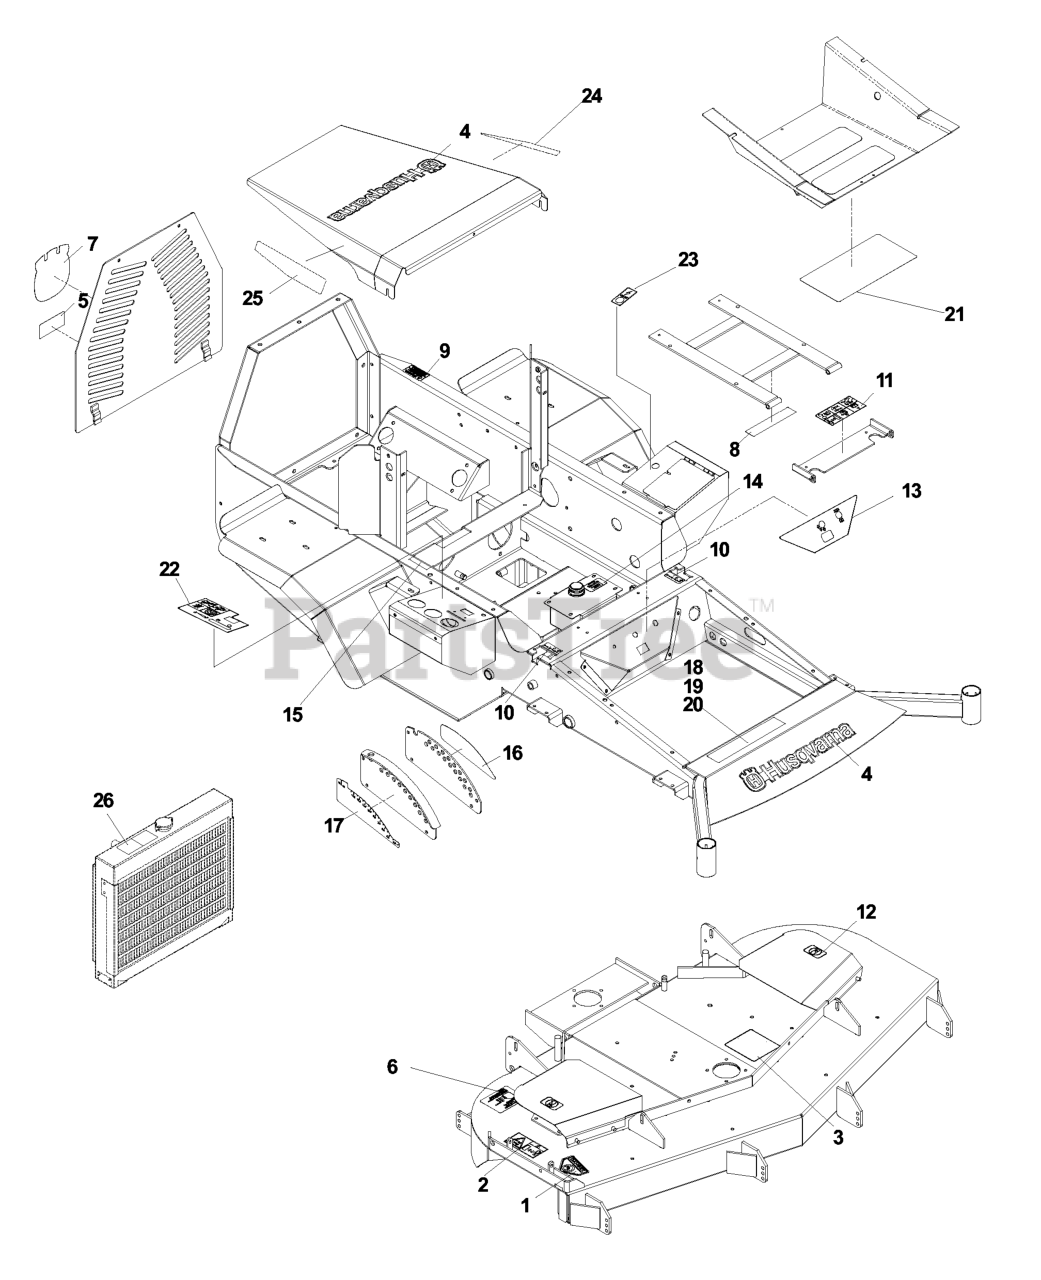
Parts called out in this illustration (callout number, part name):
1	DECAL, CPSC
2	DECAL, EURO SEVERING
3	DECAL, BELT ROUTING
4	DECAL, HUSQVARNA 17.5"
5	DECAL, BELT DRIVE
6	DECAL, ANTI SCALP
7	DECAL, LGE CROWN 7X6"
8	EURO DECAL-BATTERY WARNIN6
9	DECAL, PROP. 65
10	DECAL, MOTION CONTROL
11	DECAL, EURO WARNING
12	DECAL, NO STEP
13	DECAL, FRONT CONSOLE
14	DECAL, MOBIL 1
15	FUEL VALVE DECAL
16	DECAL, HEIGHT
17	DECAL, HEIGHT
18	DECAL - BZ6134D
19	DECAL - BZ7234D
20	DECAL - BZ6127D
21	DECAL, SERVICE
22	DECAL, RT CONSOLE
23	DECAL, 12V
24	DECAL, 34 TURBO LH
24	DECAL, 27HP DIESEL LEFT
25	DECAL, 34 TURBO RH
25	DECAL, 27HP DIESEL - RIGHT
26	DECAL, HOT
26	DECAL, EXHAUST
